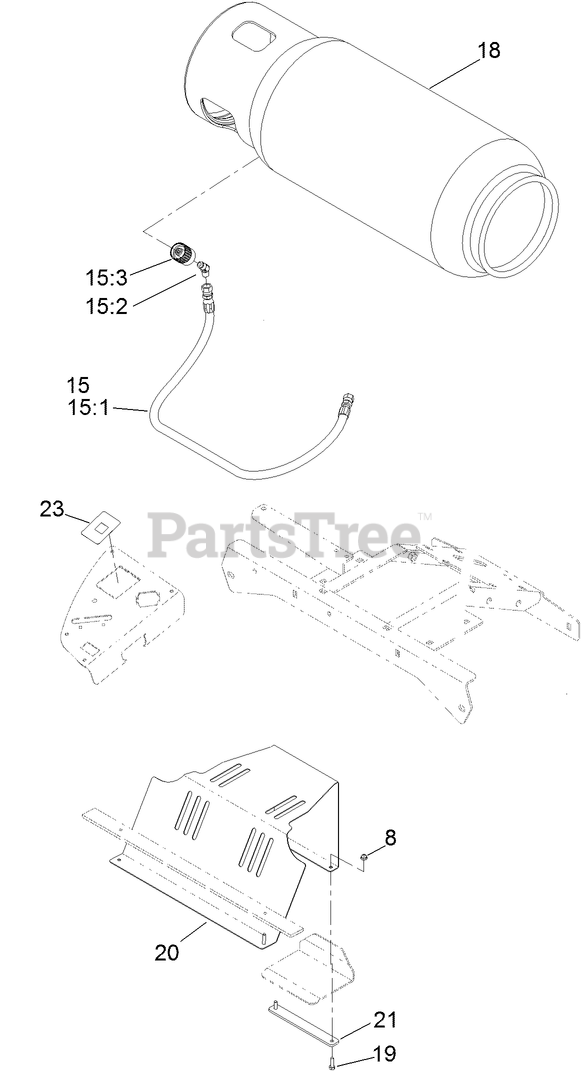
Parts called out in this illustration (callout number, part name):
8	NUT-HF
15	LPG HOSE ASM
15:1	LPG FUEL HOSE ASM
15:2	ELBOW-45 DEG
15:3	CONNECTOR-LPG TANK, LH THREAD
18	TANK-LPG
19	SCREW-HH
20	SHEILD-FAN
23	DECAL-METER, HOUR
